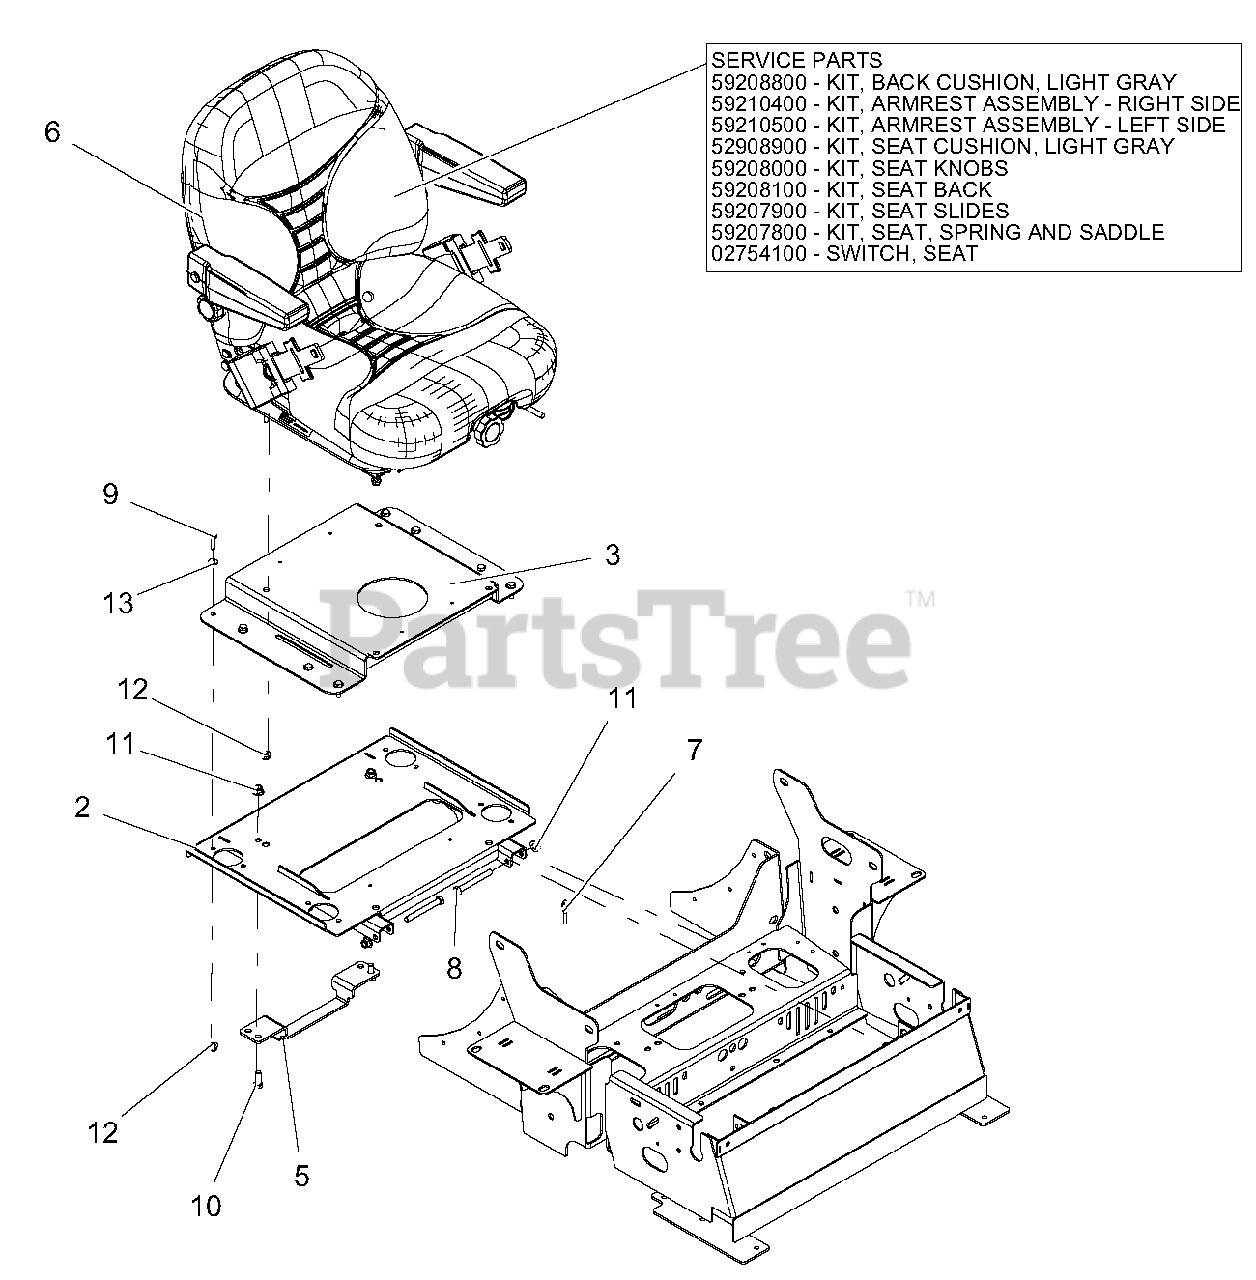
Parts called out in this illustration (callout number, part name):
2	WLDMT, SEAT ISO MOUNTING-RED
3	WLDMT, SEAT BASE MOUNTING-RED
5	BRKT, SEAT LATCH-BLACK
6	SEAT, SUSPENSION W/SEAT BELT, LT GRAY
7	CABLE TIE W/ TREE (.25 HOLE)
8	BLT-HEX .38-16X3.25 GR5 YWZC
9	BLT-HEX .31-18X1.00 GR5 YWZC
10	BLT-HEX .38-16X1.00 GR5 YWZC
11	NUT-LK-NYL-FLG .38-16 YWZC
12	NUT-LK-NYL-FLG .31-18 YWZC
13	@WSHR-FL-STL.344X.688X.065YWZC
